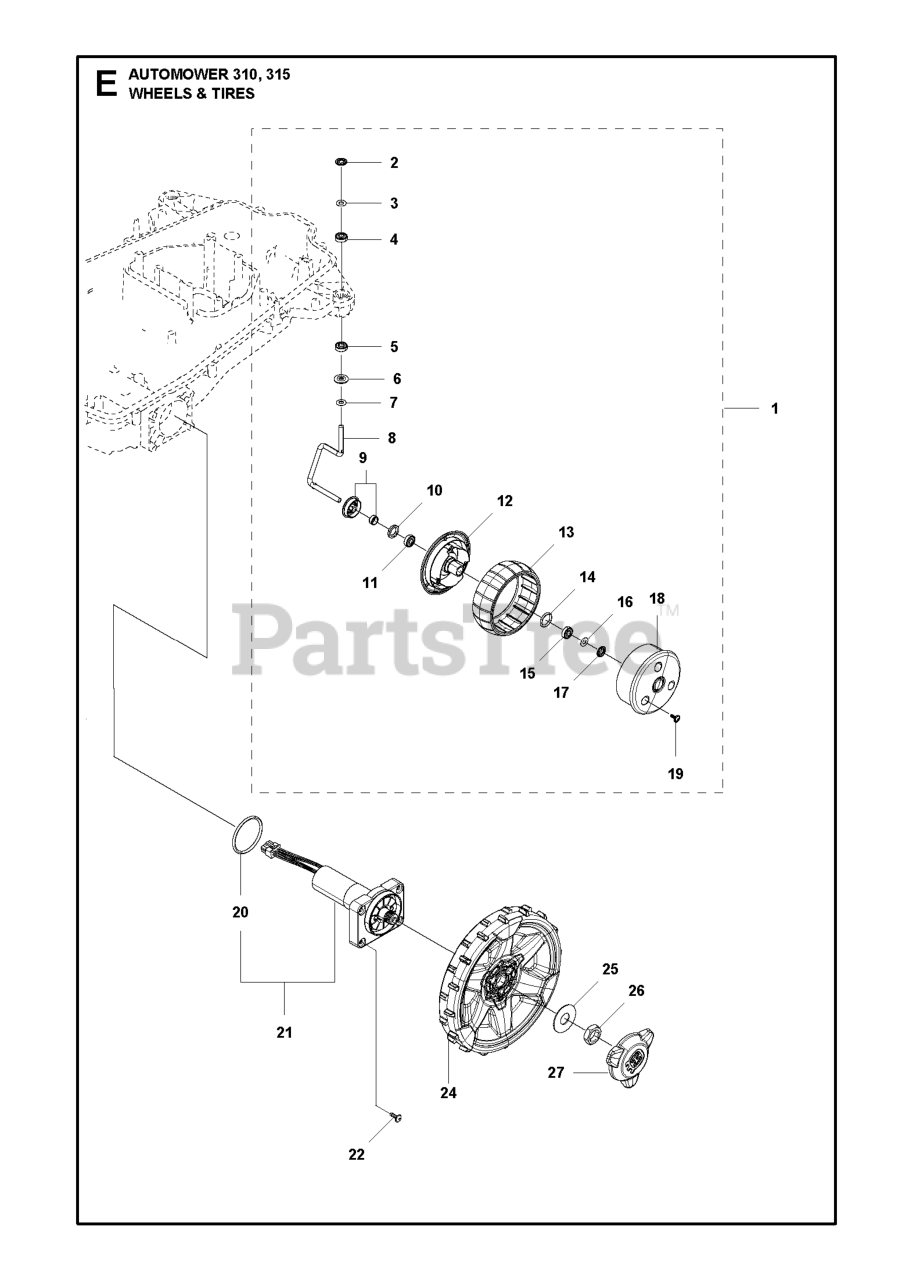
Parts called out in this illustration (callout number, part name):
1	WHEEL KIT FRONT
2	LOCKWASHER STARLOCK SS 6MM GEO
3	WASHER FRONT WHEEL 6MM
4	BALL BEARING SINGLE ROW S696
5	BALL BEARING SINGLE ROW S696
6	WASHER
7	WASHER FRONT WHEEL 6MM
8	SPINDLE FRONT WHEEL 6 MM
9	SHIELD KIT
10	SEALING 12X18X3
11	BALL BEARING SINGLE ROW S696
12	WHEEL FRONT WHEEL INSIDE
13	WHEEL RUBBER TYRE
14	O-RING 2,62X15,54
15	BALL BEARING SINGLE ROW S696
16	WASHER FRONT WHEEL 6MM
17	LOCKWASHER STARLOCK SS 6MM GEO
18	WHEEL FRONT WHEEL OUTSIDE
19	SCREW 14MM
20	O-RING LIGHT GREY
22	SCREW ITXPANT
25	WASHER WASHER REAR WHEEL 16X40
26	HEXAGON THIN NUT
27	HUB CAP REAR WHEEL NO CENTER P
